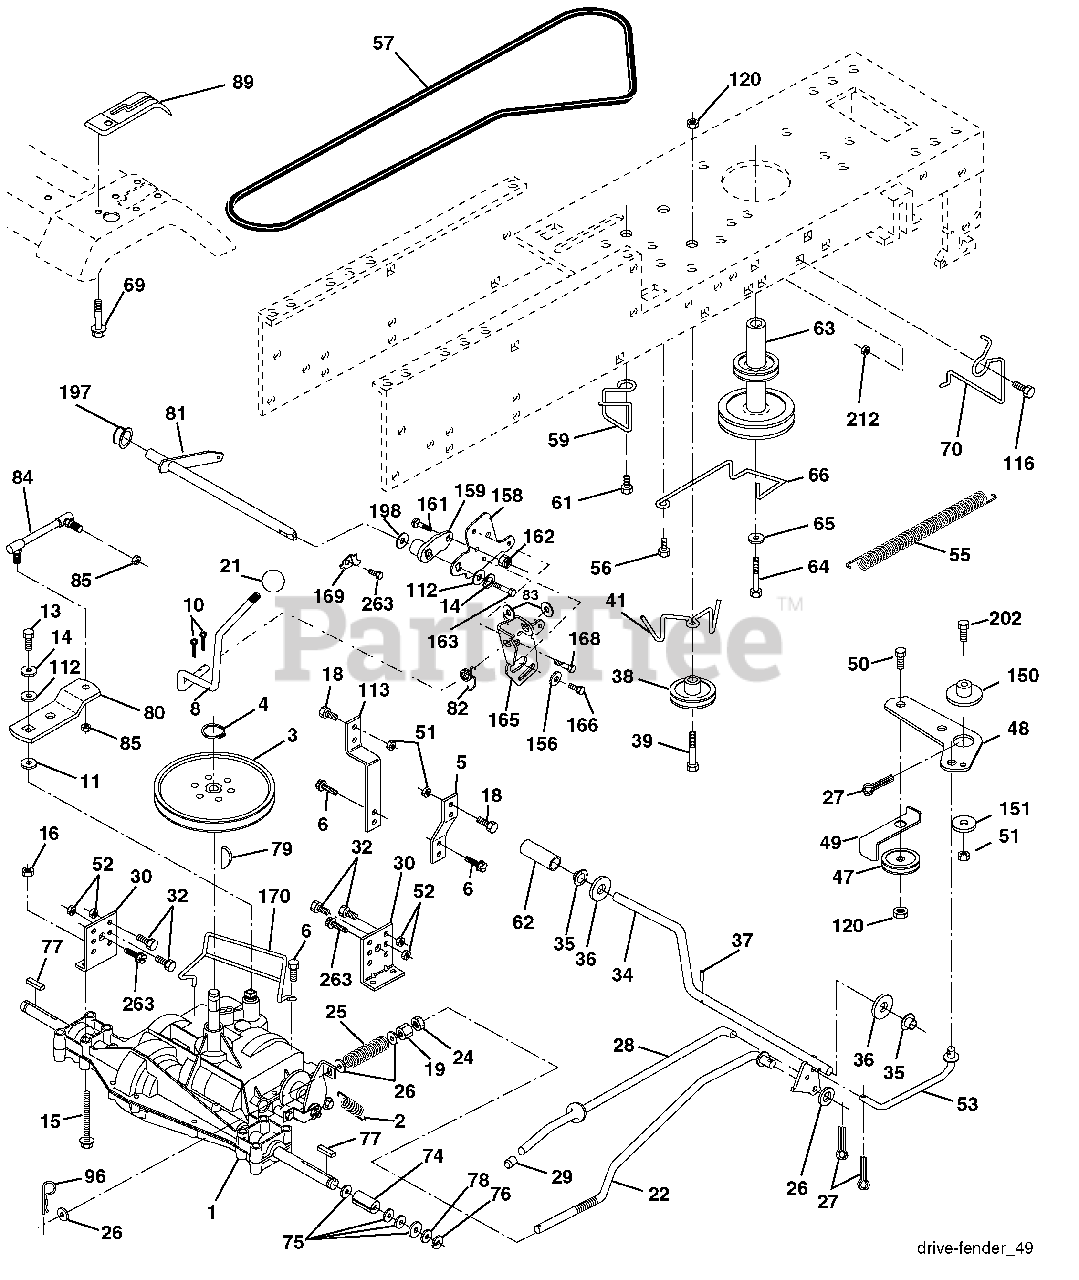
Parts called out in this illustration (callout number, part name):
2	Spring Return Brake
3	Pulley Transaxle 18"tires
4	Ring Retainer # 5100-62
5	Strap Torque 30 Degrees RH
6	Screw 5/16-18 x 3/4
8	Rod Shifter Blk
10	Pin Cotter 1/8 x 1 Cad
11	Washer Plate Shf 388 Sq Hole
13	Bolt 1/4-28 unf Gr. 8 w/Patch
14	Washer Lock Hvy Helical 1/4
15	Bolt Hex Flghd 5/16-18 Gr. 5
16	Nut 5/16-18
18	Bolt Fin Hex 3/8-16 unc x 1 Gr. 5
19	Nut lock Hex w/Ins 3/8-16 Unc
21	Knob
22	Rod Brake LT
24	Nut Hex Jam 3/8-16 unc
25	Spring Rod Brake 2 00 Zinc
26	Washer 13/32 x 13/16 x 16 Ga.
27	Pin Cotter 1/8 x 3/4 Cad
28	Rod Brake Parking LT/YT
29	Cap Brake Parking Black
30	Bracket Transmission
32	Bolt Fin Hex 5/16-18 x 3/4
34	Shaft Asm Pedal Foot Nibbed
35	Bearing Nylon Blk 629 Id
36	Washer 21/32 x 1 x 16 Ga.
37	Pin Roll 3/16 x 1"
38	Pulley Composite Flat
39	Bolt 3/8-16 x 2-3/4
41	Keeper Belt Idler
47	Pulley Idler V Groove Plastic
48	Bellcrank Clutch Grnd Drv STL
49	Retainer Belt Style Spring
50	Bolt Carr Sh 3/8-16 x 1-1/2 Gr. 5
51	Nut Crownlock 3/8-16 unc
52	Nut Crownlock 5/16-18 unc
53	Link Clutch
55	Spring Return Clutch 6 75
56	Screw 3/8-16 x 1-1/4
57	V-Belt Ground Drive 95
59	Keeper Belt Chassis Span Ctr
61	Screw 3/8-16 x .875
62	Cover Pedal Blk Round
63	Engine Pulley LT/YT
64	Bolt Hex 7/16-20 x 4 Gr. 5
65	Washer Lock Hvy Hlcl Spr 7/16
66	Keeper Belt Engine
69	Screw 1/4 x 1/2 unc
70	Guide Belt Mower Drive RH
74	Spacer Axle
75	Washer 25/32 x 1 1/4 x 16 Ga.
76	E-ring #5133-75
77	Key Square 2 0 x 1845/ 1865
78	Washer 25/32 x 1-5/8 x 16 Ga.
79	Key Woodruff
80	Arm Shift Transaxle
81	Shaft Asm Cross Taper
82	Spring Torsion Shift
83	Washer 17/32 x 3/4 x 16 Ga.
84	Link Transaxle
85	Nut Lock Center 1/4-28
89	Console Shift
96	Retainer Spring 1"
112	Washer 9/32 x 3/4 x 10 Ga.
113	Strap Torque 90 Degrees LH
116	Bolt Rdhd Sq Neck 3/8-16 x 1
120	Nut Lock Flg 3/8-16
150	Spacer Retainer Lt
151	Washer 13/32 x 2 x 10 Ga.
156	Washer Srrrtd 5/16 ID x 1.0 x .125
158	Bracket Shift Mount
159	Hub Shift
161	Bolt 1/4-20 x 3/4 Gr. 5
162	Nut Crownlock 1/4-20 unc
163	Bolt Hex Fin 1/4-20 unc x 1 Gr. 5
165	Bracket Pivot Lever
166	Screw 5/16-18 x 5/8
168	Bolt Shoulder 5/16-18 x .561
169	Plate Fastening
170	Keeper, Belt Transaxle
197	Nyliner Snap-In 5/8
198	Washer Nylon
202	Bolt Carr Sh 3/8-16 x 1-3/4 Gr. 5
212	Nut Hex Flg Lock
263	Screw 3/8-16 x 3/4
